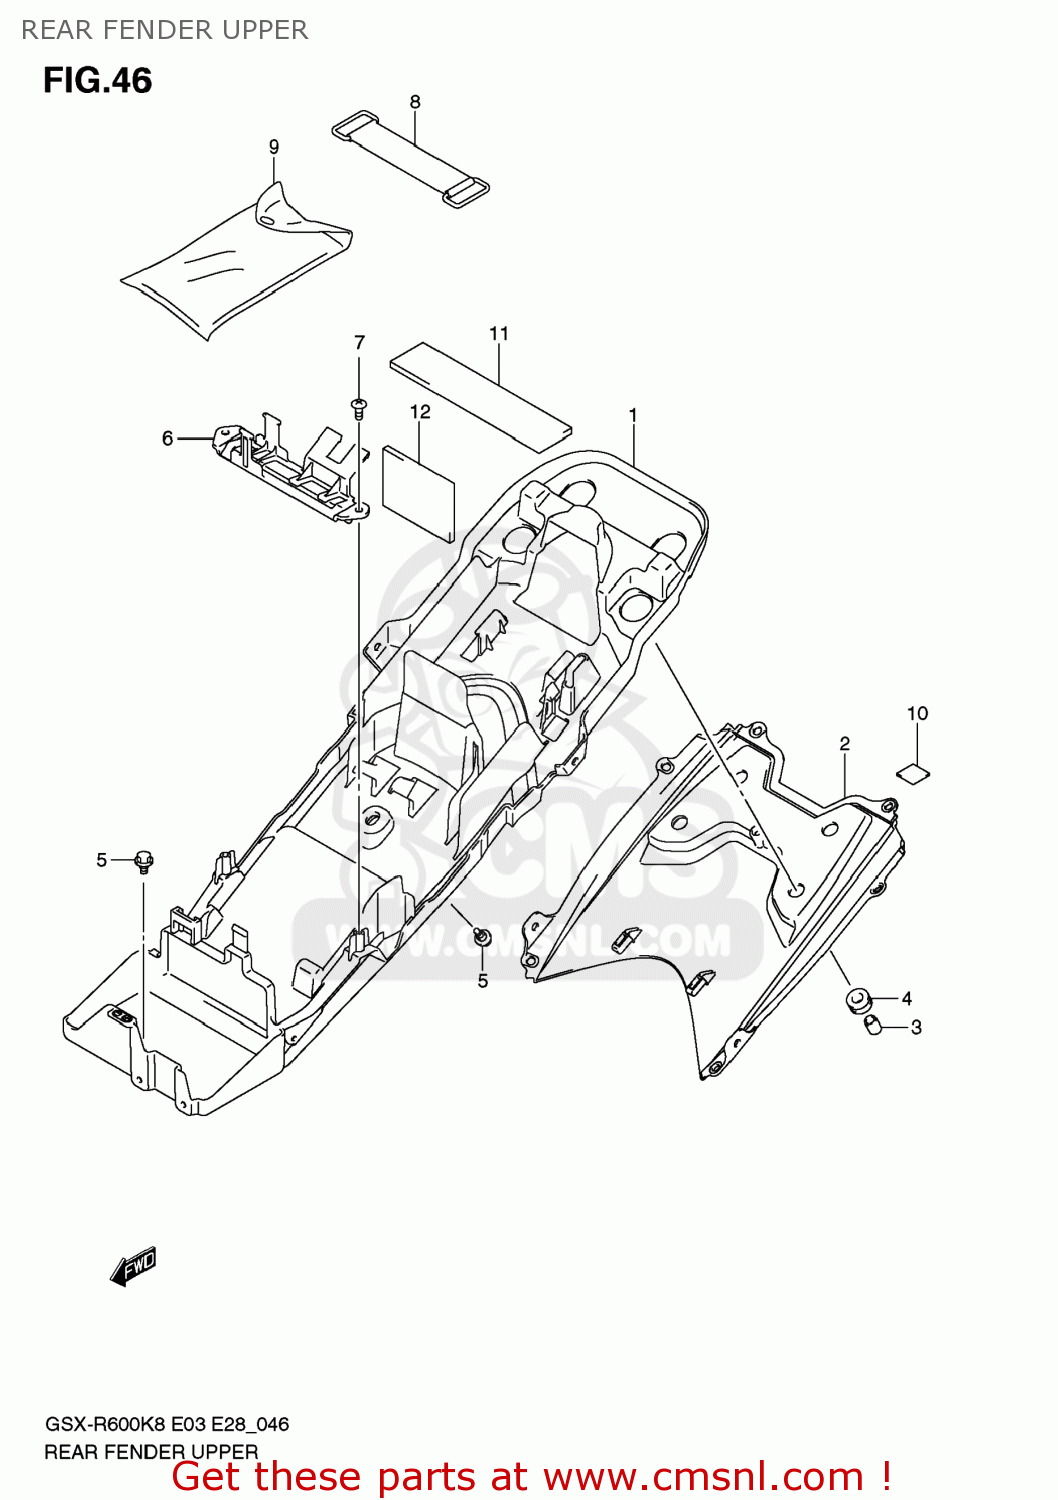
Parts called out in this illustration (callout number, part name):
1	FENDER,RR FR
2	COVER,RR FENDER FR
3	SPACER(6.5X9X13.5)
4	CUSHION
5	BOLT
6	BRACKET,ELECTRIC PARTS HOLDER
7	SCREW
8	BAND
9	TOOL ASSY
10	CUSHION,RR COVER NO.2
11	PROTECTOR,20X9
12	CUSHION,RR FENDER
